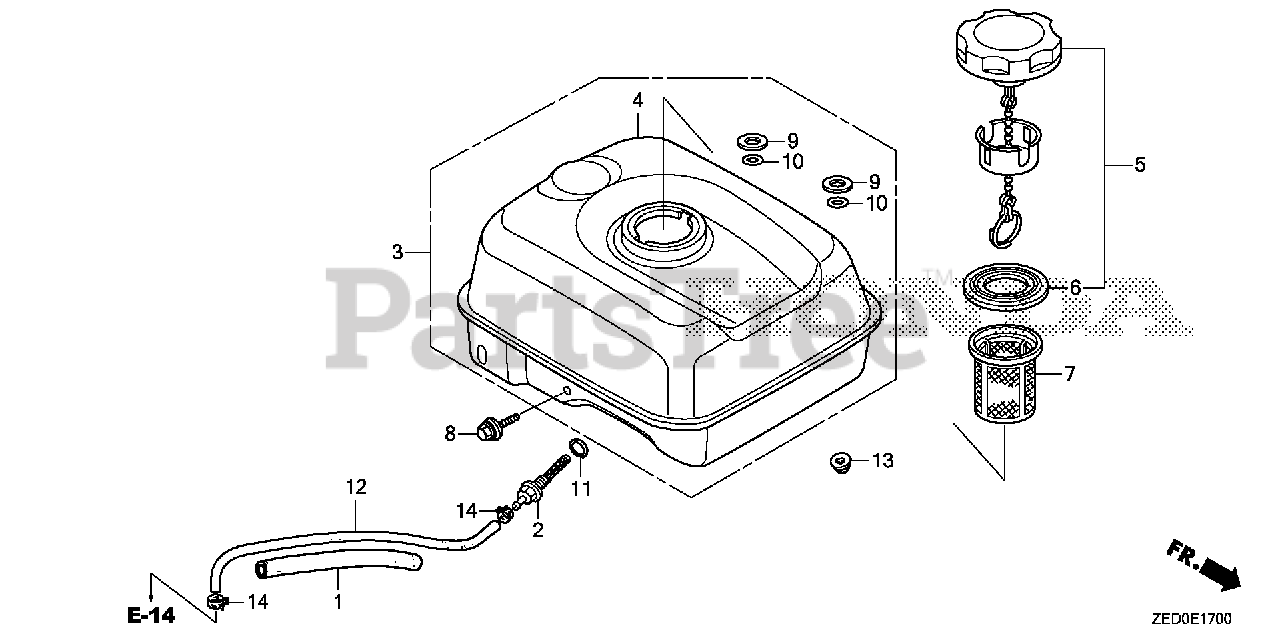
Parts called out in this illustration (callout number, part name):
1	RUBBER, SUPPORTER (107MM)
2	JOINT, FUEL TANK
4	TANK, FUEL *NH31* (MCKINLEY WHITE)
4	TANK, FUEL *NH1* (BLACK)
5	CAP, FUEL FILLER
6	GASKET, FUEL FILLER CAP
6	GASKET, FUEL FILLER CAP (39X62X3) (TOUYOUSYA)
8	BOLT, FLANGE (6X29)
11	O-RING (14MM) (ARAI) Use up to Engine SN 2949254.
11	O-RING (14MM) (NOK)
12	TUBE, FUEL (4.5X145) (FKM)
13	NUT, FLANGE (6MM)
14	CLIP, TUBE (D8)
